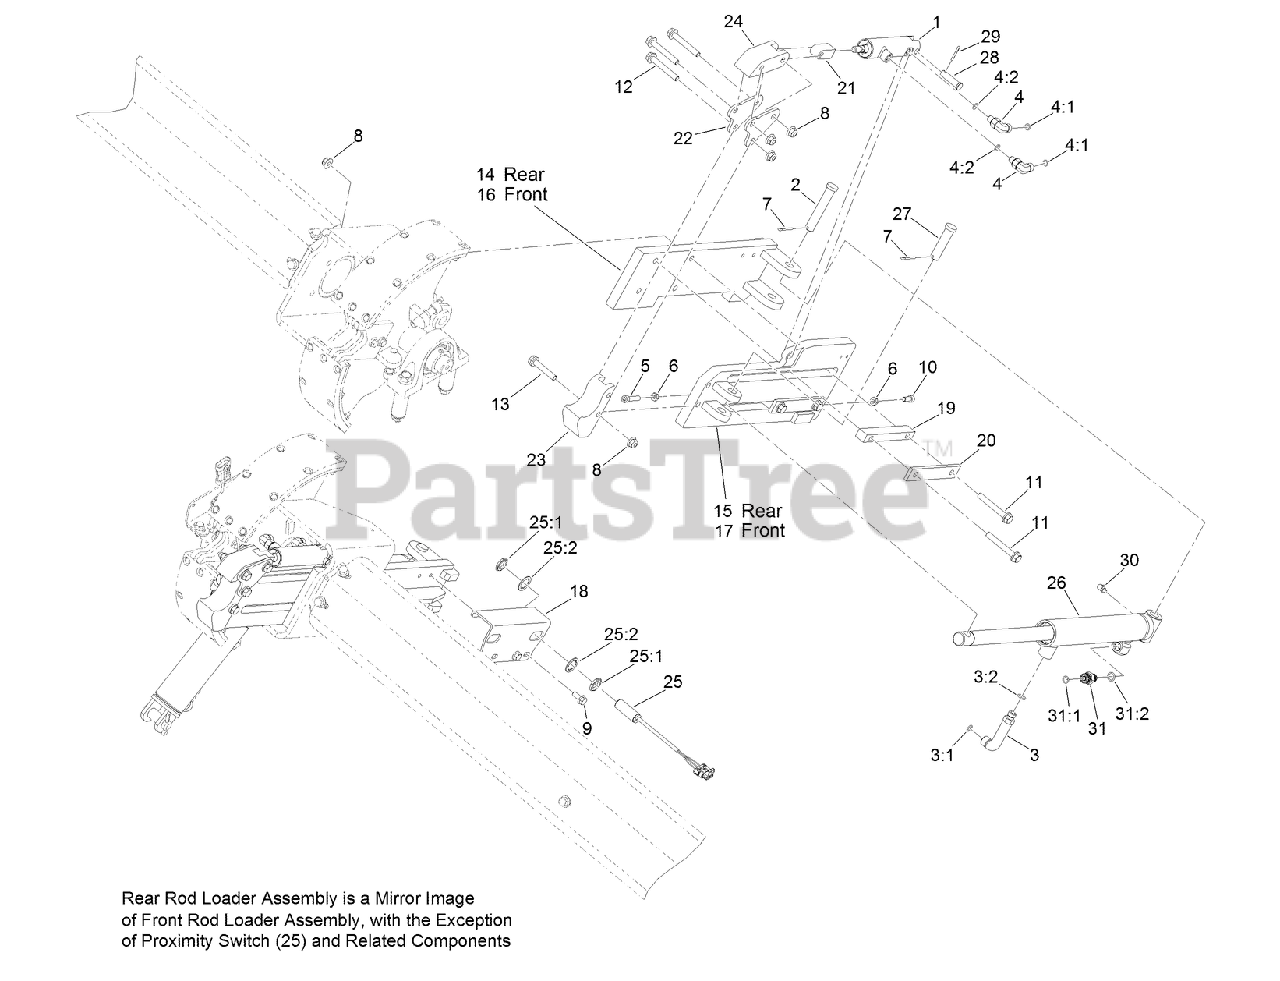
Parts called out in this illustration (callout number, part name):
1	HYD CYLINDER ASM
2	PIN-CLEVIS
3	FITTING-HYD, 90 DEG
3:1	O-RING
3:2	O-RING
4	FITTING-ELBOW, 90 DEG
4:1	O-RING
4:2	O-RING
5	SCREW-HSH
6	NUT-JAM
7	PIN-COTTER
8	NUT-HF, NI
9	SCREW-HHF
10	SCREW-HSH
11	SCREW-HFH
12	SCREW-HHF
13	SCREW-HHF
14	ARM-EXTENSION, REAR
15	SLIDER-REAR
16	ARM-EXTENSION, FRONT
17	SLIDER-FRONT
18	PLATE-MOUNT, SENSOR
19	GUIDE-ARM, EXTENSION
20	CAP-GUIDE, EXTENSION ARM
21	ROD-EYE, CYLINDER
22	PLATE-GRIPPER, ROTATE
23	INSERT-GRIPPER, FIXED
24	INSERT-GRIPPER, ROTATE
25	PROXIMITY SWITCH ASM
25:1	NUT-HEX
25:2	WASHER-LOCK, INTERNAL TOOTH
26	CYLINDER-HYDRAULIC
27	PIN-CLEVIS
28	PIN-CLEVIS
29	PIN-COTTER
30	FITTING-GREASE, 90 DEG
31	FITTING-STRAIGHT
31:1	O-RING
31:2	O-RING
